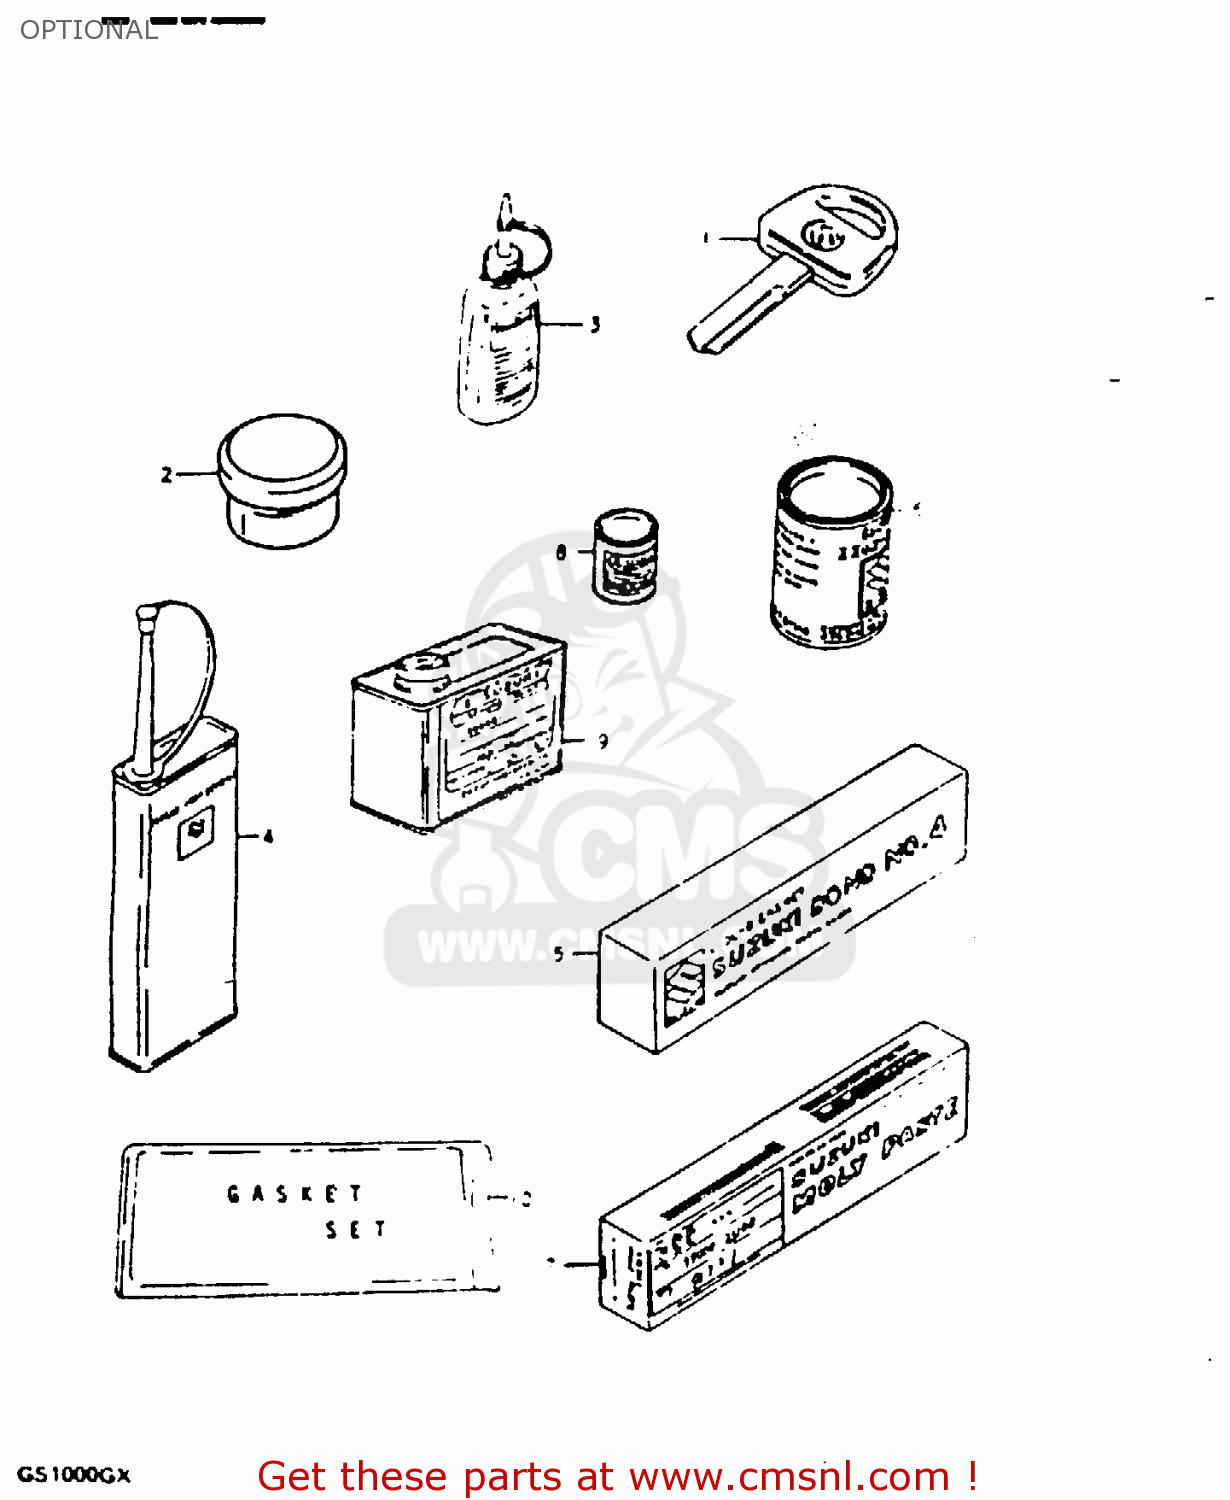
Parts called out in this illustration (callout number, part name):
1	KEY,BLANK
2	GREASE,PBC FOR BRK PAD 20G
3	THREAD LOCK NO.1342
4	THREAD LOCK NO.1401 CLEAR 200G
5	BOND 1104
6	GREASE(C)EP2 LITHIUM 150G
7	SUZUKI MOLY PASTE
8	PAINT,BLACK
9	PAINT (BLACK)
10	GASKET SET (MCA)
